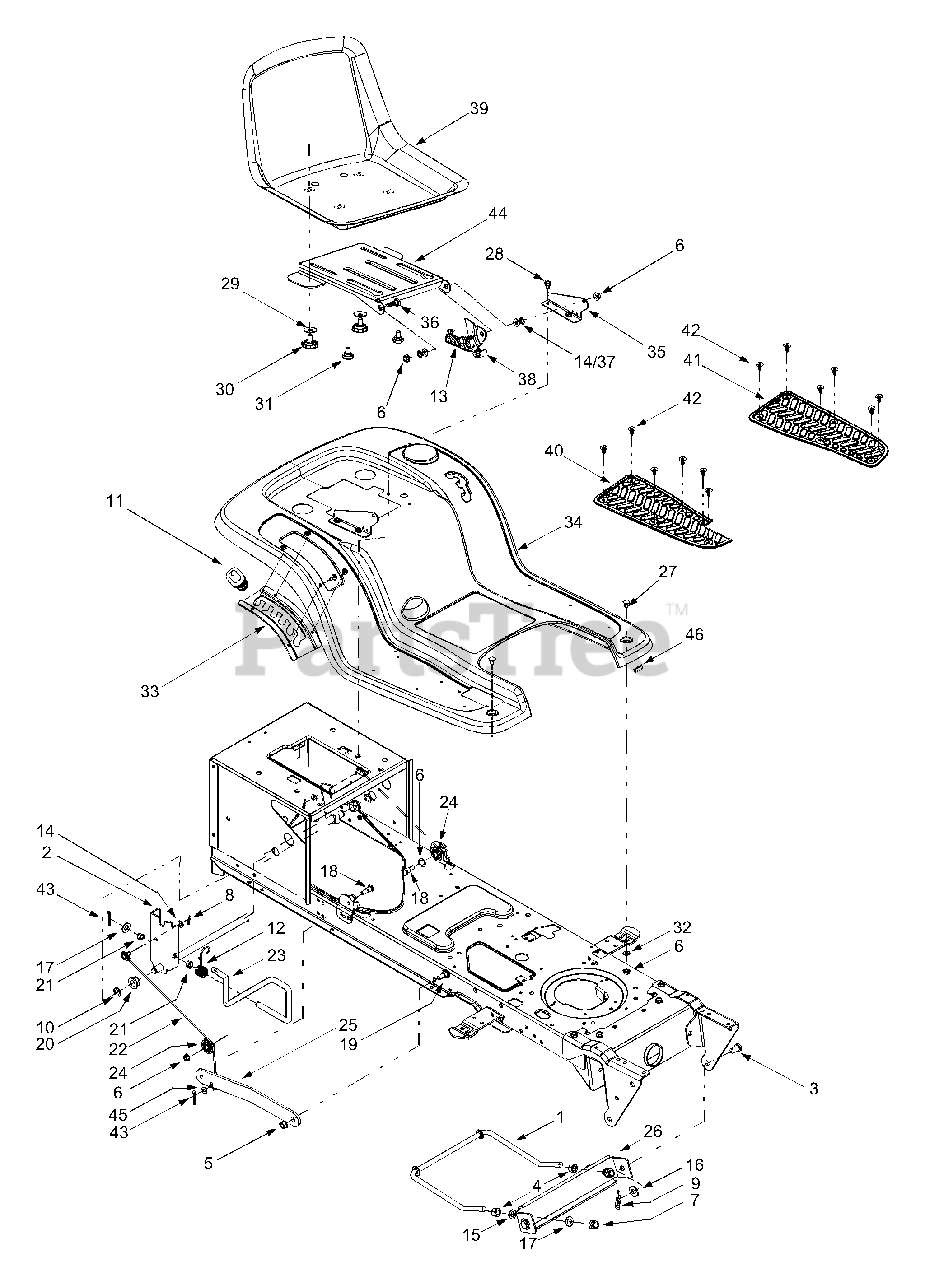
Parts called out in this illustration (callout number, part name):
1	Deck Stabilizer Rod
3	Clevis Pin, .5 x .78
4	Hex Nut, 1/2-13
5	Flange Lock Nut, 3/8-16
6	Flange Lock Nut, 5/16-18
7	Hex Nut, 1/2-13
8	Internal Cotter Pin
9	Internal Cotter Pin
10	E-ring
11	Handle Grip
12	Torsion Spring
13	Extension Spring, .84 x 4.6
14	Flat Washer, 5/16
15	Lock Washer, 1/2
16	Flat Washer, .531 x 1.062 x .134
17	Flat Washer, .51 x 1.12 x .06
18	Hex Cap Screw, 5/16-18 x .62
19	Shoulder Screw, 3/8-16
20	Hex Flange Bearing
21	Snap Flange Bearing
22	Lift Cable, 16.16 (T604G)
22	Lift Cable, 15.62 (T604H)
23	Lift Handle
24	Roller Pulley
27	Carriage Bolt, 5/16 x .62
28	Self-tapping Screw, 5/16-18 x .625
29	Bell Washer, .390 x 1.13 x .062
30	Knob, 3/8-16
31	Shoulder Screw
32	Flat Washer, .349 x 1.0 x .063
36	Shoulder Screw
37	Speed Clip
38	Seat Lift Bracket
39	Medium Back Seat, Yellow
40	RH Foot Pad, Rubber
41	LH Foot Pad, Rubber
42	Foot Pad Clips
43	Cotter Pin
45	Flat Washer, .344 x .62
46	Trim Strip
